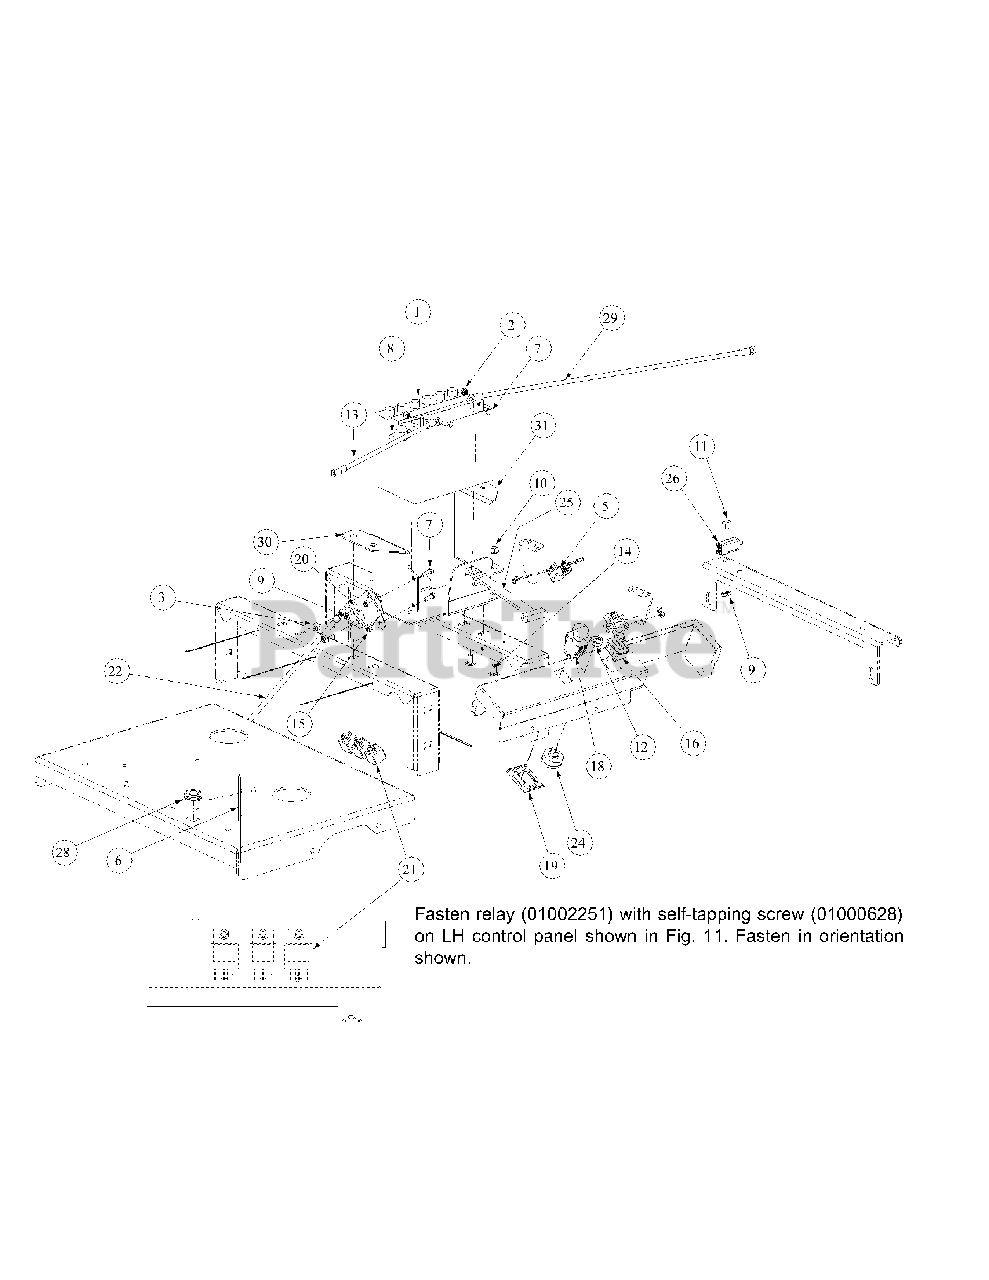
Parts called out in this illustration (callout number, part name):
1	Battery, 12V 225CCA 30 Min
2	Hex Flange Lock Nut, 1/4-20
3	Nylock Nut, 5/16-18
5	Switch, Safety
6	Tie, Cable, 3/16 x .05 x 7.4"
7	Screw, Hex, Cap, 1/4-20 x .75
8	Boot, 1" OD Rubber Battery-PST, Red
9	Nut, Lock, Nylon Insert, #10-32
10	Nut, Hex, Flange Lock, 3/8-16
11	Screw, Phillips Head, Machine, 10-32 x 5/8
12	Nut, W/Cap, 5/8-32 Ignition
13	Cable, Battery, Red, 15"
14	Carriage Bolt, 3/8-16 x .75 LG.
15	Lock Nut w/Nylon Insert
16	Meter, Hour
18	Switch, Electric, PTO
19	Bracket, PTO Switch Retainer
20	Solenoid Magnetic Switch
21	Relay, 12V 40A
22	Cable, Battery Red, 32"
24	Switch, Ignition, 6 Pin
24	Key, Ignition
25	Strap, Battery
26	Switch, Plunger
28	Grommet, .75 ID
29	Cable, Battery Black, 24"
30	Mount Bracket, Battery
31	Mount Bracket, Battery
